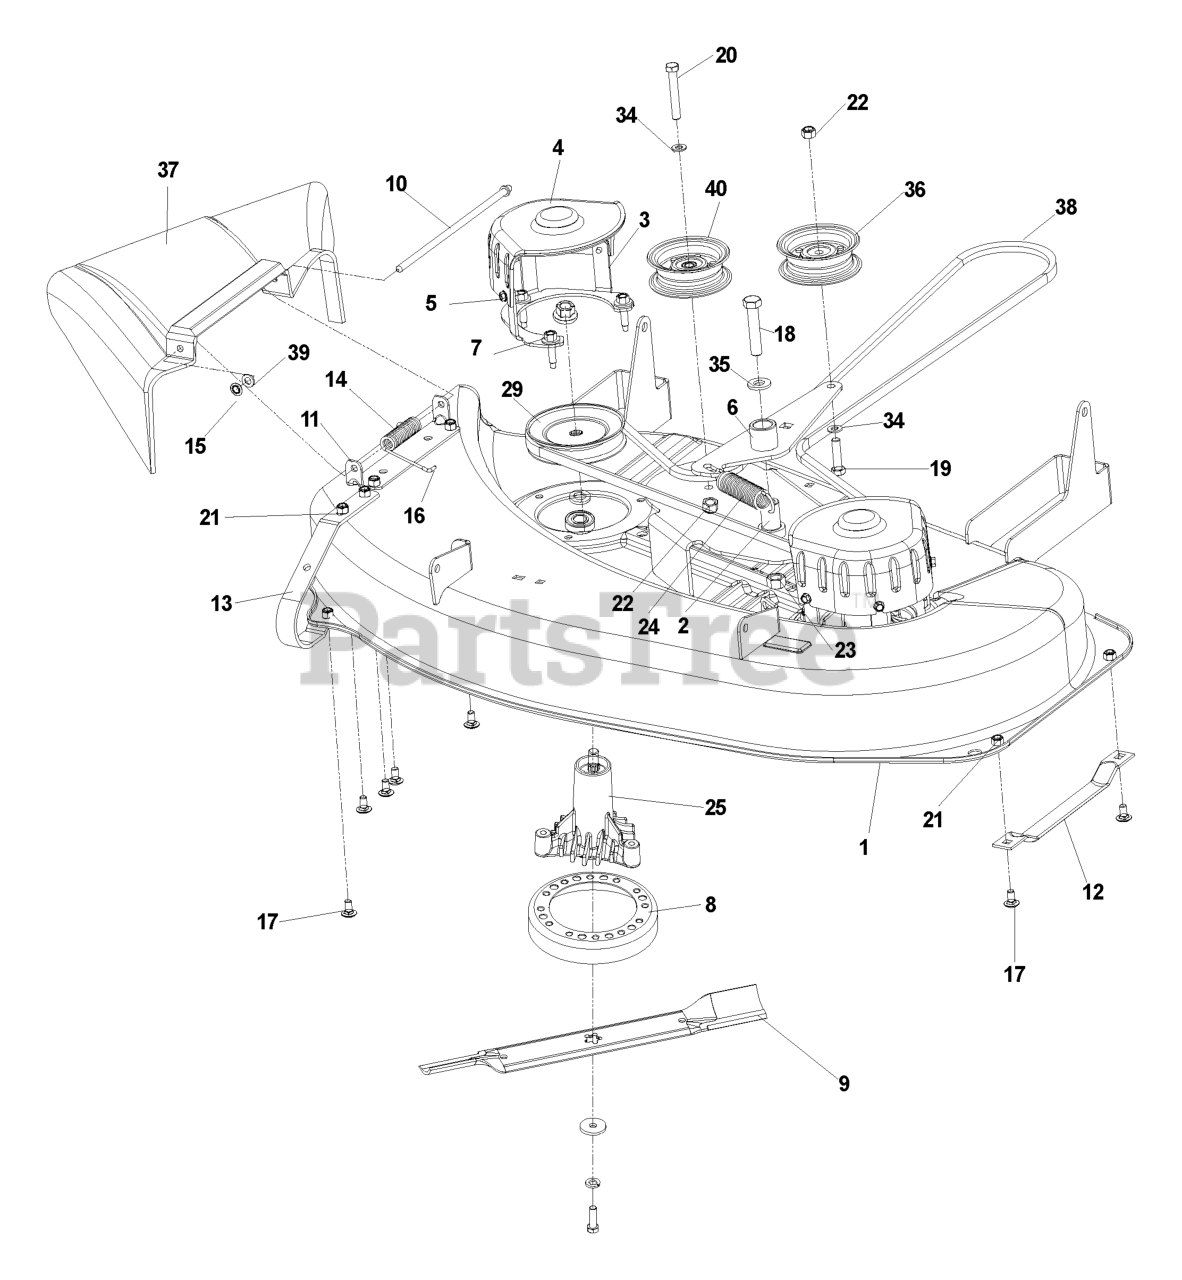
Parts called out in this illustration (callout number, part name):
1	DECK W/DECALS 38" ORANGE
2	IDLER SPINDLE
3	SPINDLE COVER ANCHOR
4	SPINDLE COVER
5	SCREW 1/4 X 5/8
6	DECK IDLER ARM WELDMENT
7	WASHER HEAD SCREW
8	STRIPPER-ROUND-UNIVERSAL
9	BLADE 38" MULCHING STD
10	ROD, HINGE
11	BRACKET, MOWER DEFLECTOR
12	RUNNER LH
13	RUNNER RH
14	SPRING, TORSION DEFLECTOR
15	PUSH NUT
16	CAP-SLEEVE
17	CARRIAGE BOLT 5/16C X 5/8"
18	HCS 1/2C X 2 3/4
19	HCS 3/8C X 1 1/2
20	HCS 3/8C X 2 1/2
21	NUT 5/16 NYLOC
22	NUT 3/8-16 NYLOC
23	NUT 1/2-13 HEX NYLOC ZD
25	SPINDLE, MANDREL ASM
29	PULLEY MANDREL
34	WASHER 3/8 SAE FLAT
35	WASHER 1/2" FLAT
36	PULLEY, IDLER, SHORT
37	SHEILD DEFLECTOR
39	WASHER, 11/32 X 5/8 X 16 GA
40	PULLEY, IDLER
